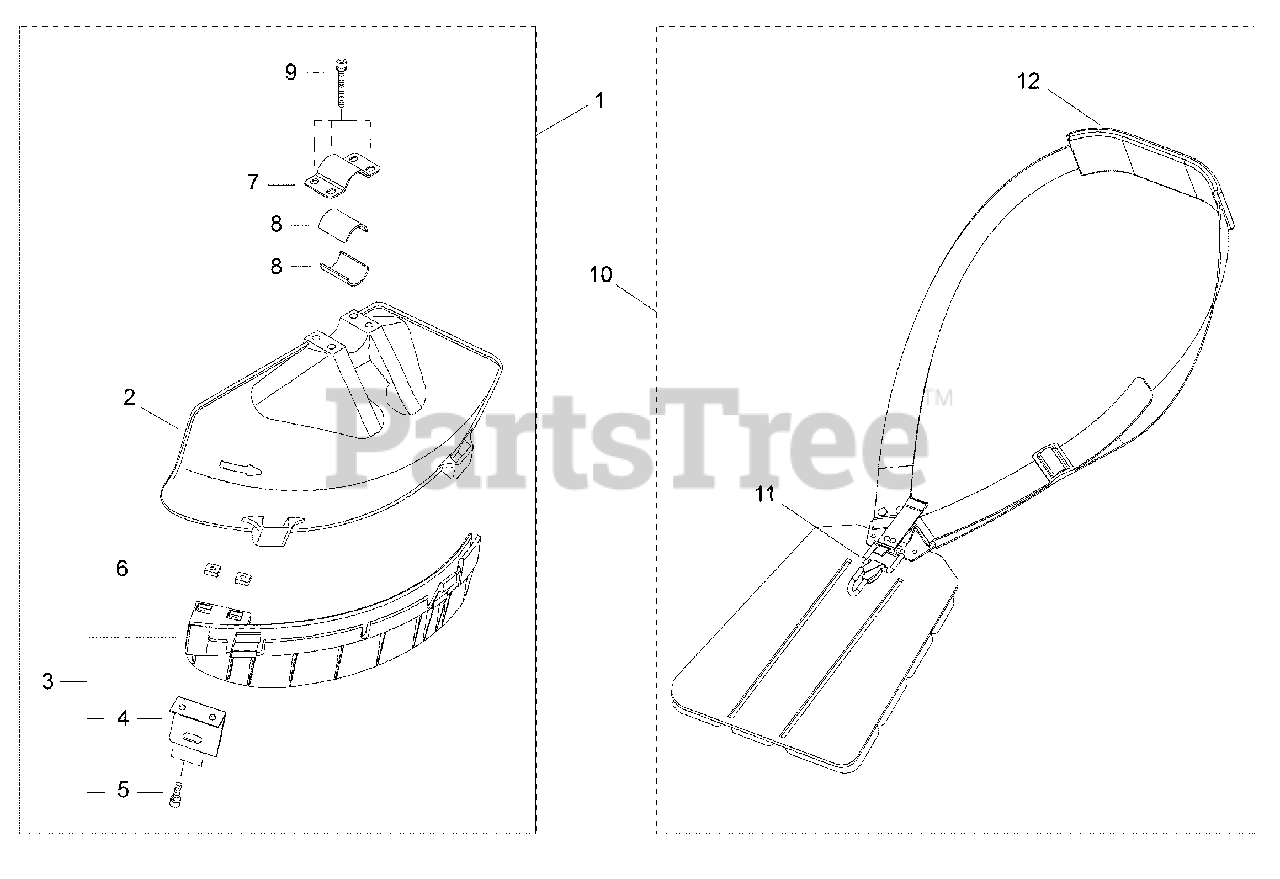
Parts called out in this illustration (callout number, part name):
1	DEBRIS SHIELD KIT
2	SHIELD, DEBRIS
3	SHIELD GUARD KIT
4	KNIFE, TRIMMER LINE
5	SCREW - 5X16
6	NUT - 5
7	CLAMP - UPPER
8	SPACER
9	SCREW - 5X45
10	HARNESS ASSY
11	HOOK
12	PAD
